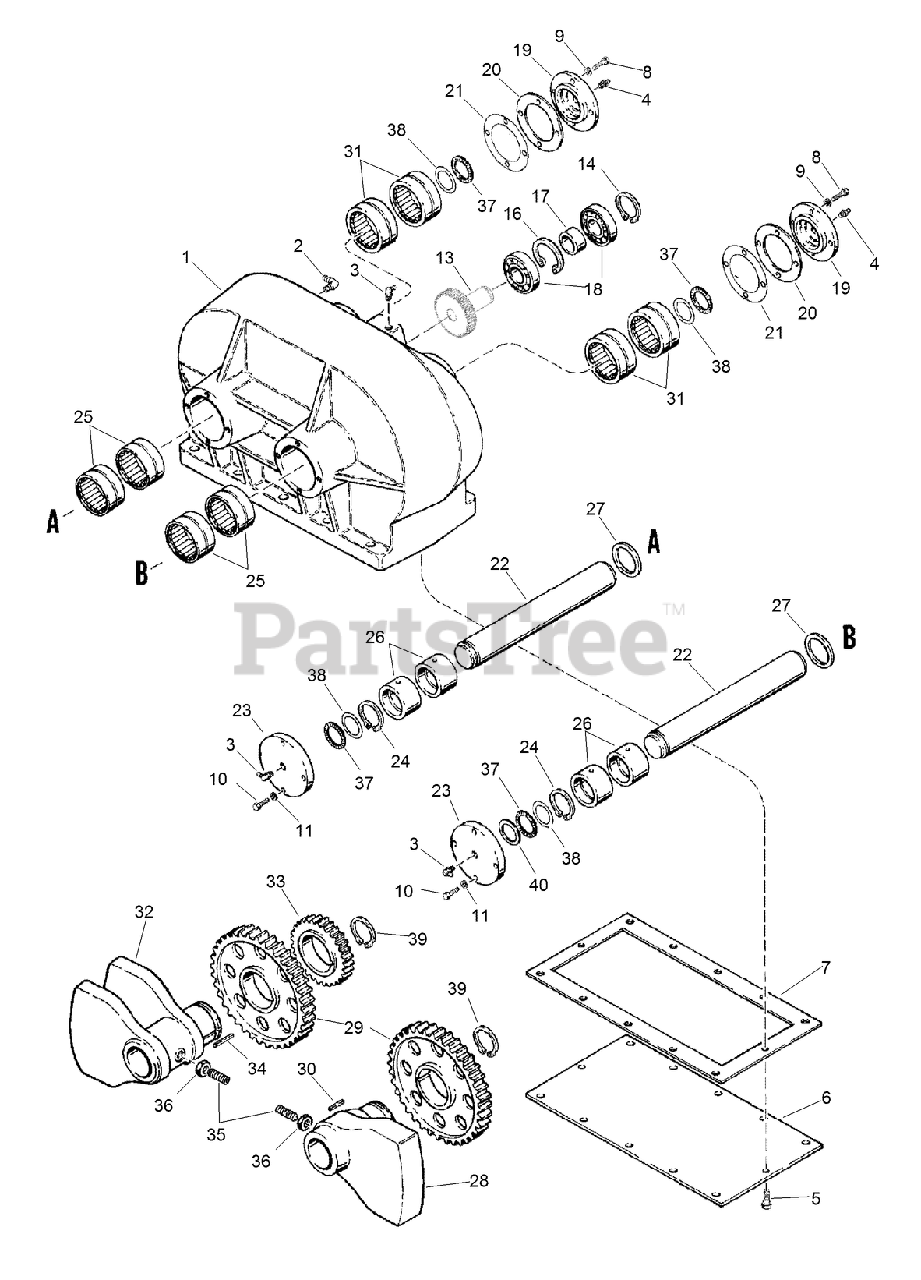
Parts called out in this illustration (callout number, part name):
1	CASE-GEAR
2	FITTING-ELBOW, 90 DEG
3	FITTING - Grease, 90 Degree, 1/4-28 Taper x 3/4 inch
4	FITTING-Lube 1/4-28 Tpr SAE-LT .54 Long
5	SCREW-HH
6	PLATE-COVER, GEARBOX
8	SCREW-HH
9	WASHER-Lock, 5/16 inch
10	SCREW-HH
11	WASHER-Lock, 5/16 inch
13	GEAR-DRIVE
14	RING-snap
16	RING-internal retaining, No. 315, bearing and shaft retaining
18	BEARING
19	CAP-BEARING
20	GASKET-COVER
21	GASKET-COVER
23	CAP-BEARING, LARGE
24	RING-RETAINING
25	BEARING-ROLLER (MATCHED SET)
26	RACE-BEARING (MATCHED SET)
28	WEIGHT-SHAKER
31	BEARING-ROLLER (MATCHED SET)
32	WEIGHT-SHAKER
33	GEAR-DRIVEN
35	SCREW-HSH
36	NUT-HEX, JAM
37	BEARING-THRUST, NEEDLE
38	WASHER-THRUST
39	RING-RETAINING
40	WASHER-THRUST
